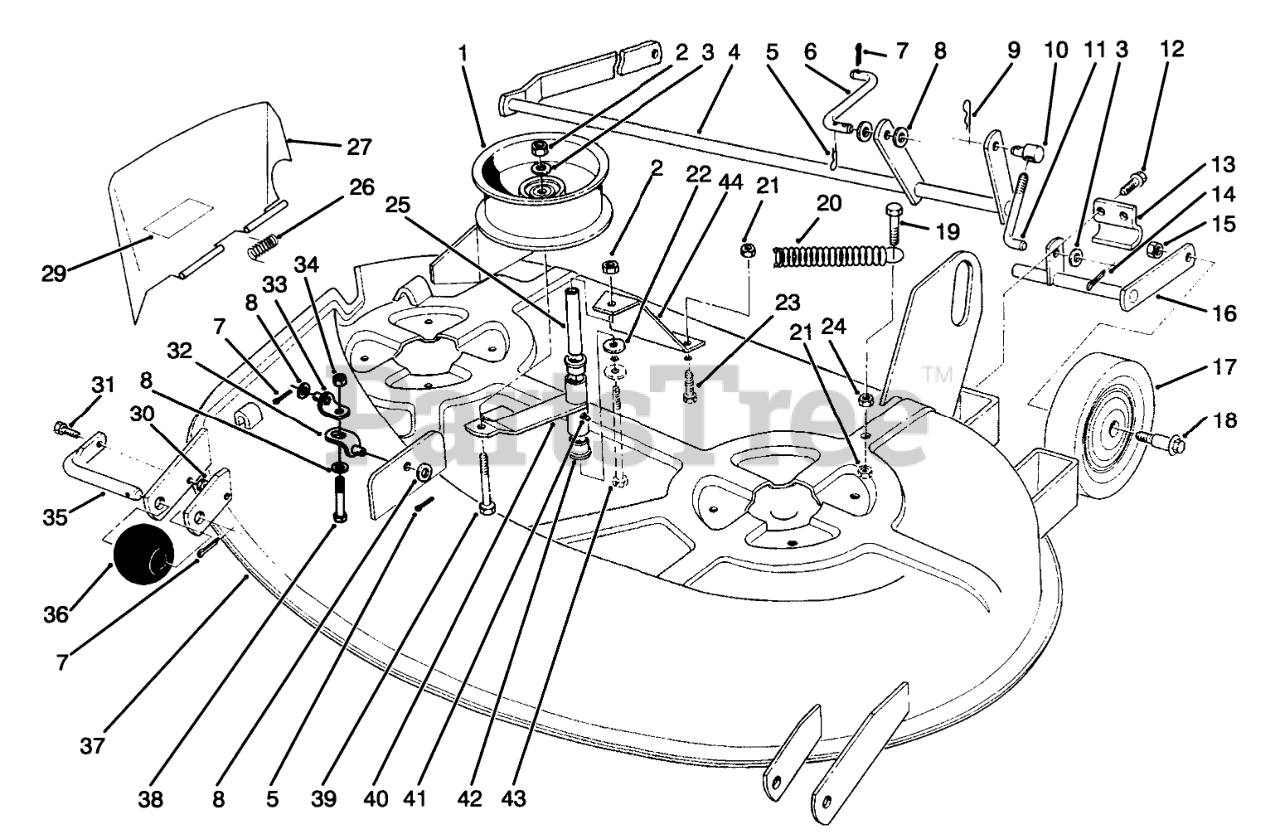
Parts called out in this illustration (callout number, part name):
1	Pulley-Idler
2	NUT-LOCK, NI
3	WASHER-FLAT
4	Shaft-R.H.
5	PIN-COTTER
6	LINK-REAR
7	PIN-COTTER, HAIR
8	WASHER-FLAT
9	Hairpin
10	TRUNNION
11	ROD-LIFT
12	Bolt
13	Camp
14	PIN-COTTER
15	Nut-Hex
16	Shaft-L.H.
17	WHEEL
18	BOLT-SHOULDER
19	SCREW-HH
20	SPRING-EXTENSION
21	NUT-LOCK, NI
22	WASHER
23	SCREW-HH
24	NUT-HEX
25	SPACER
26	SPRING-TORSION
27	DISCHARGE CHUTE/DECAL
29	DECAL-DANGER, THROWN OBJECT
30	NUT-LOCK, NI
31	SCREW-HH
32	BRACKET-LIFT, LOWER
33	BRACKET-LIFT, UPPER
34	NUT-JAM
35	SHAFT-ROLLER
36	ROLLER
37	38 DECK W/DECALS
38	SCREW-HH
39	SCREW-HH
40	Arm-Idler
41	FITTING-GREASE
42	BUSHING
43	SCREW-HH
44	Brace
